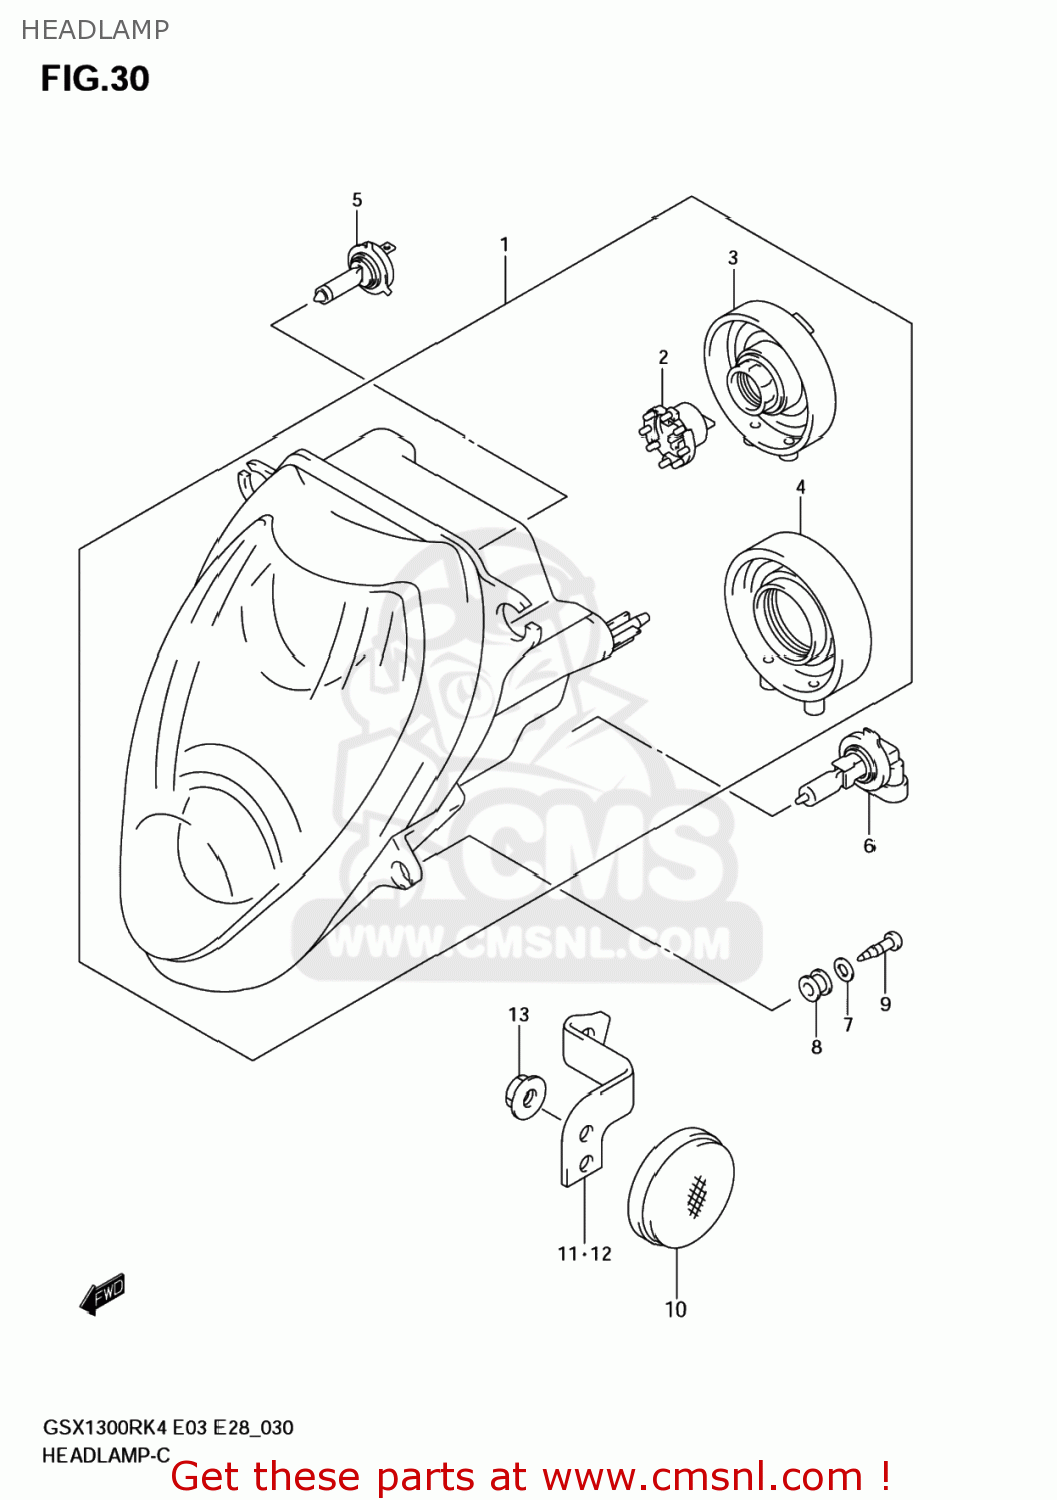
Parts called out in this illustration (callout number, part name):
1	HEADLAMP ASSY
2	ADAPTER ASSY
3	SOCKET,COVER
4	SOCKET,COVER
5	BULB(12V55W/H7/PX26D/PHILIPS)
6	BULB(12V60W,HB3,#9005)
7	WASHER(5.5X18X1)
8	CUSHION
9	SCREW
10	REFLECTOR,REFLEX
11	BRACKET,FR SIDE RR,R
12	BRACKET,FR SIDE RR,L
13	NUT
